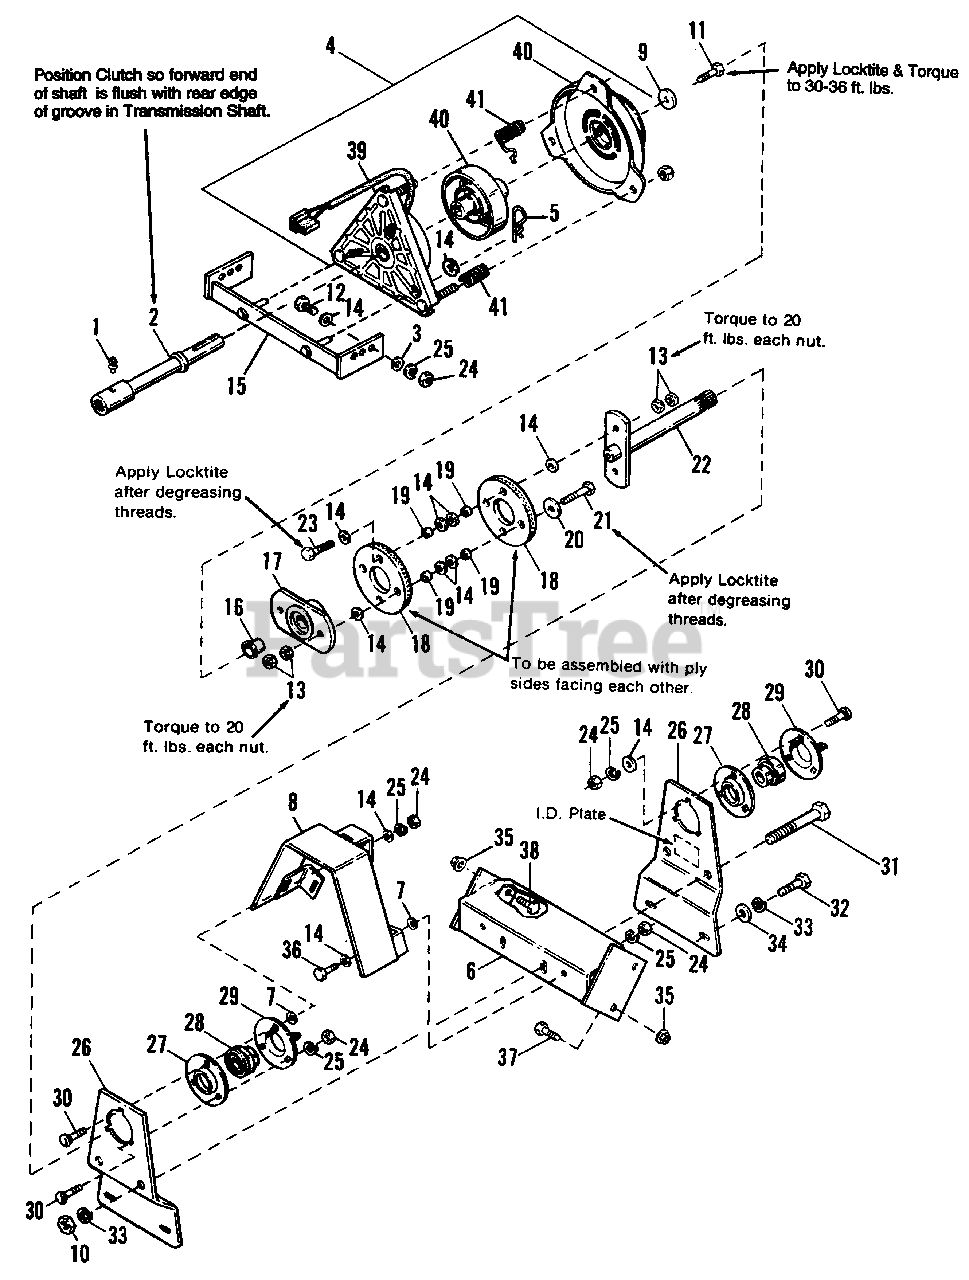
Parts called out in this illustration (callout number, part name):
1	FITTING, Grease
2	SHAFT ASSY.
3	WASHER, Plain, 11/32 x 1 x 1/8
4	ELECTRIC CLUTCH
5	CLIP, Hair Pin
6	BRACKET ASSY.
7	NUT, Push Pal, 5/16
8	GUARD ASSY.
9	WASHER, 13/32 x 1-1/2 x 1/4
10	NUT, Hex, 1/2-13
11	CAPSCREW, Hex Hd., 3/8-16 x 1, Gr. 5
12	CAPSCREW, Hex Hd., 5/16-18 x 1
13	NUT, Hex, Centerlock, 5/16-18
14	WASHER, Plain, 11/32 ID x 3/4 OD x 1/16
15	PLATE ASSY., Rear P.T.O.
18	FLEX COUPLING
20	WASHER, Plain, 11/32 x 1-1/4 x 1/8
21	CAPSCREW, Hex Head 5/16-18 x 2 G5
22	SHAFT ASSY., P.T.O.
23	CAPSCREW, Hex Hd., 5/16-18 x 1-1/2
24	NUT, Hex, 5/6-18
25	LOCKWASHER, Spring, 5/16-18
26	SUPPORT, Rear P.T.O.
27	FLANGE, Bearing
28	BEARING, Cartridge
29	FLANGE, Bearing
30	BOLT, Carriage, 5/16-18 x 1
31	CAPSCREW, Hex Hd., 1/2-13 x 4-1/2, Gr. 5
32	CAPSCREW, Hex Hd., 1/2-13 x 1-1/2
33	LOCKWASHER, Spring, 1/2
34	WASHER, Plain, 17/32
35	NUT, Hex, Flange Whiz, 7/16-14
36	CAPSCREW, Hex Hd., 5/16-18 x 7/8, Gr. 5
37	CAPSCREW, 7/16-14 x 1-1/2, Gr. 8
38	CAPSCREW, Hex Hd., 7/16-14 x 1-1/4, Gr. 8
39	FIELD ASSY.
40	ROTOR, ARMATURE & BRAKE ASSY.
41	ACCESSORY KIT
